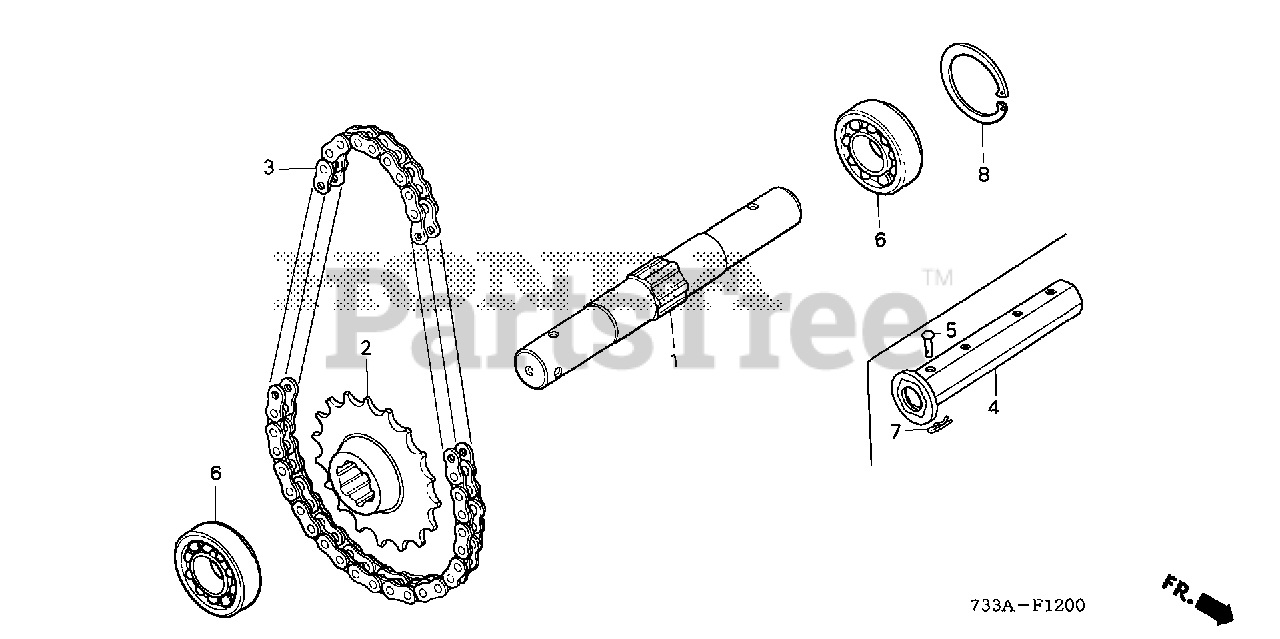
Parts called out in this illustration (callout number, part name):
1	SHAFT, WHEEL
2	SPROCKET, DRIVEN (18T)
3	CHAIN, FINAL
4	SHAFT A, EXTENSION (23X32X179)
5	PIN (10X53.5)
6	BEARING, RADIAL BALL (60/32)
7	PIN, LOCK (10MM)
8	CIRCLIP, INNER (58MM)
